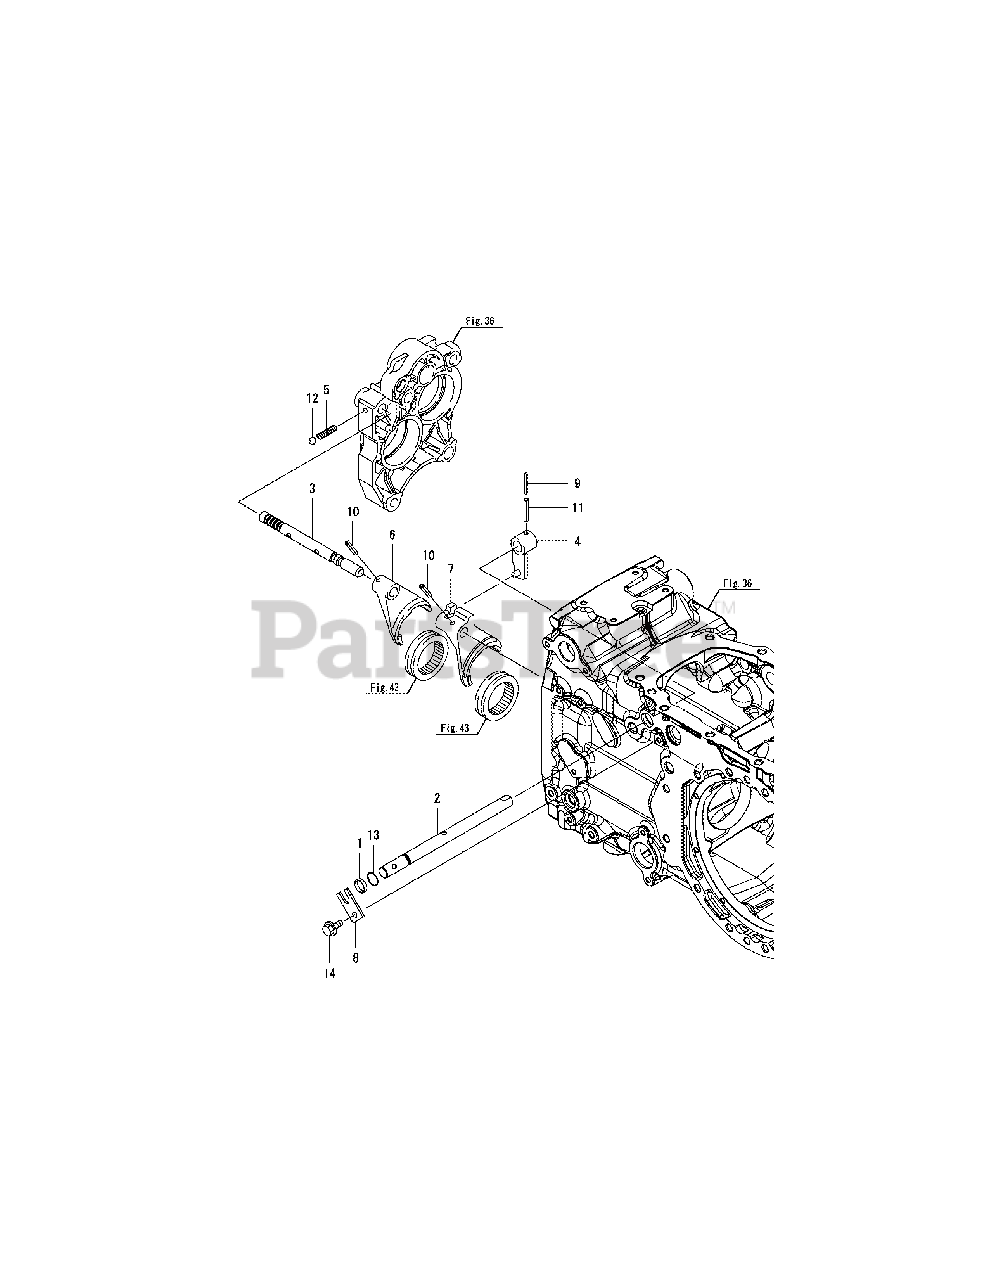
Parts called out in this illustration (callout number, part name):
2	SHAFT, RANGE SHIFT
5	SPRING, FORK LOCK
6	FORK, RANGE SHIFT
7	FORK, RANGE SHIFT
9	SPRING PIN 3.5X36
10	SPRING PIN 6X32
11	SPRING PIN 6X36
12	BALL 1/4, STEEL
13	O-RING 1A P-16.0
14	BOLT M 8X 16 PLATED
